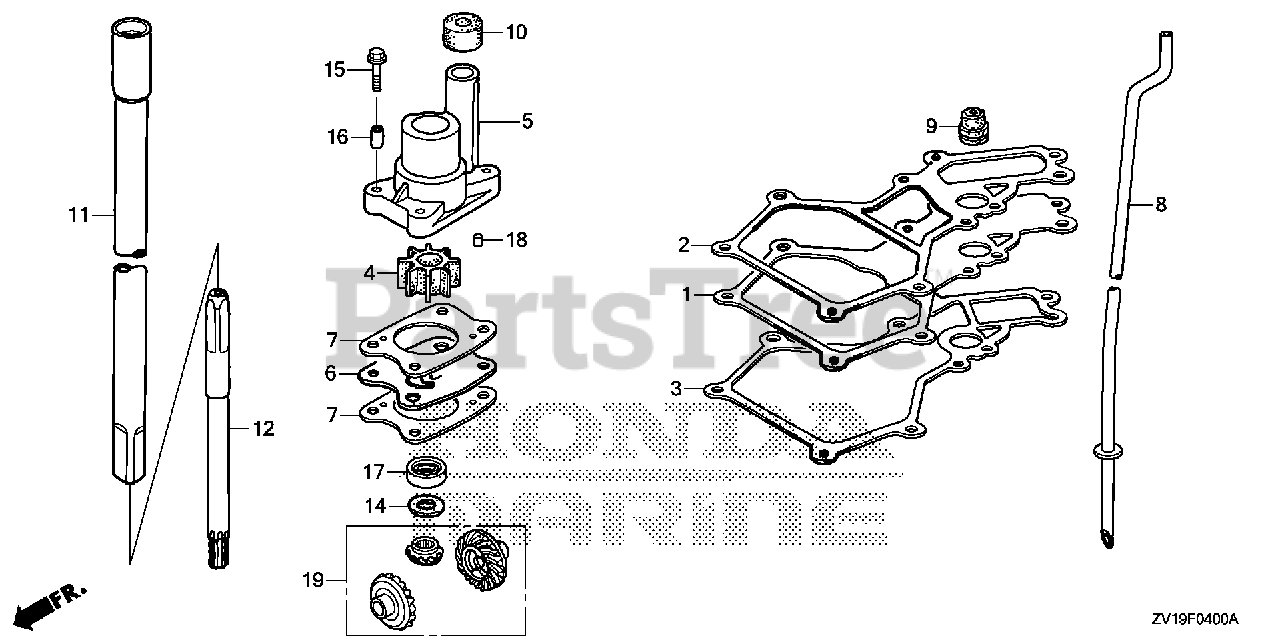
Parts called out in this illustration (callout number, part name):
1	PLATE, EX. CHAMBER
2	GASKET, EX. CHAMBER (UPPER)
3	GASKET, EX. CHAMBER (LOWER)
4	IMPELLER, PUMP
5	HOUSING, IMPELLER
6	COVER, IMPELLER
7	GASKET, IMPELLER
8	TUBE, WATER (L)
9	GROMMET, WATER TUBE
10	RING, WATER TUBE SEAL
11	SHAFT, VERTICAL (L)
12	SHAFT, PINION
14	WASHER A (1.00MM)
14	WASHER B (1.05MM)
15	BOLT-WASHER (6X29)
16	COLLAR B, DISTANCE
17	SEAL, WATER (13MM) (ARAI)
18	ROLLER (4X10)
